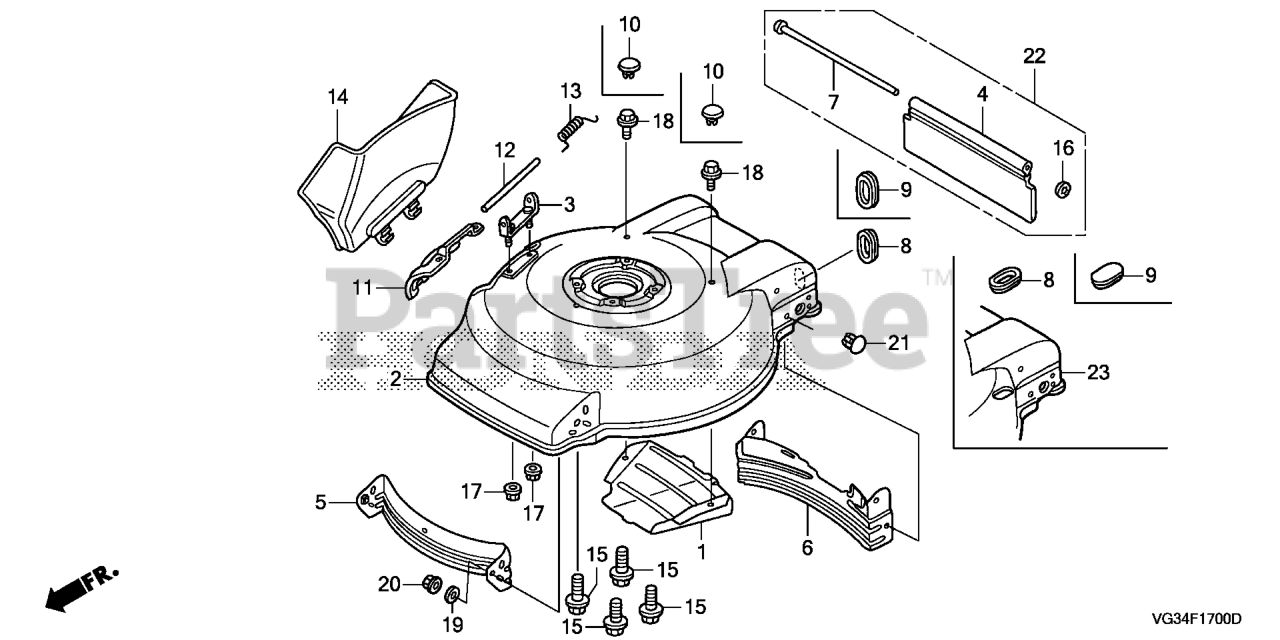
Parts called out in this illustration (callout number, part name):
3	HINGE, DISCHARGE GUARD
5	SCROLL, FR.
6	SCROLL, RR.
7	SHAFT, RR. SHIELD (405MM)
9	GROMMET, PLUG
10	PLUG, HOLE
11	GUARD *NH105*
12	SHAFT, DISCHARGE GUARD
13	SPRING, GUARD RETURN
14	CHUTE, SIDE DISCHARGE *NH105* (MAT BLACK)
15	BOLT, FLANGE (5/16-24X1")
16	NUT, PUSH (3.96MM) (FLAT ROUND TYPE)
17	NUT, FLANGE (6MM)
19	WASHER, PLAIN (5/16)
20	NUT, FLANGE (8MM)
21	PLUG, HOLE (B)
22	KIT, RR. SHIELD
23	HOUSING, CUTTER *NHC24M* (EMBOSS NEO GRAY METALLIC)
23	HOUSING, CUTTER *NHB67* (EMBOSS BRIGHT GRAY METALLIC)
